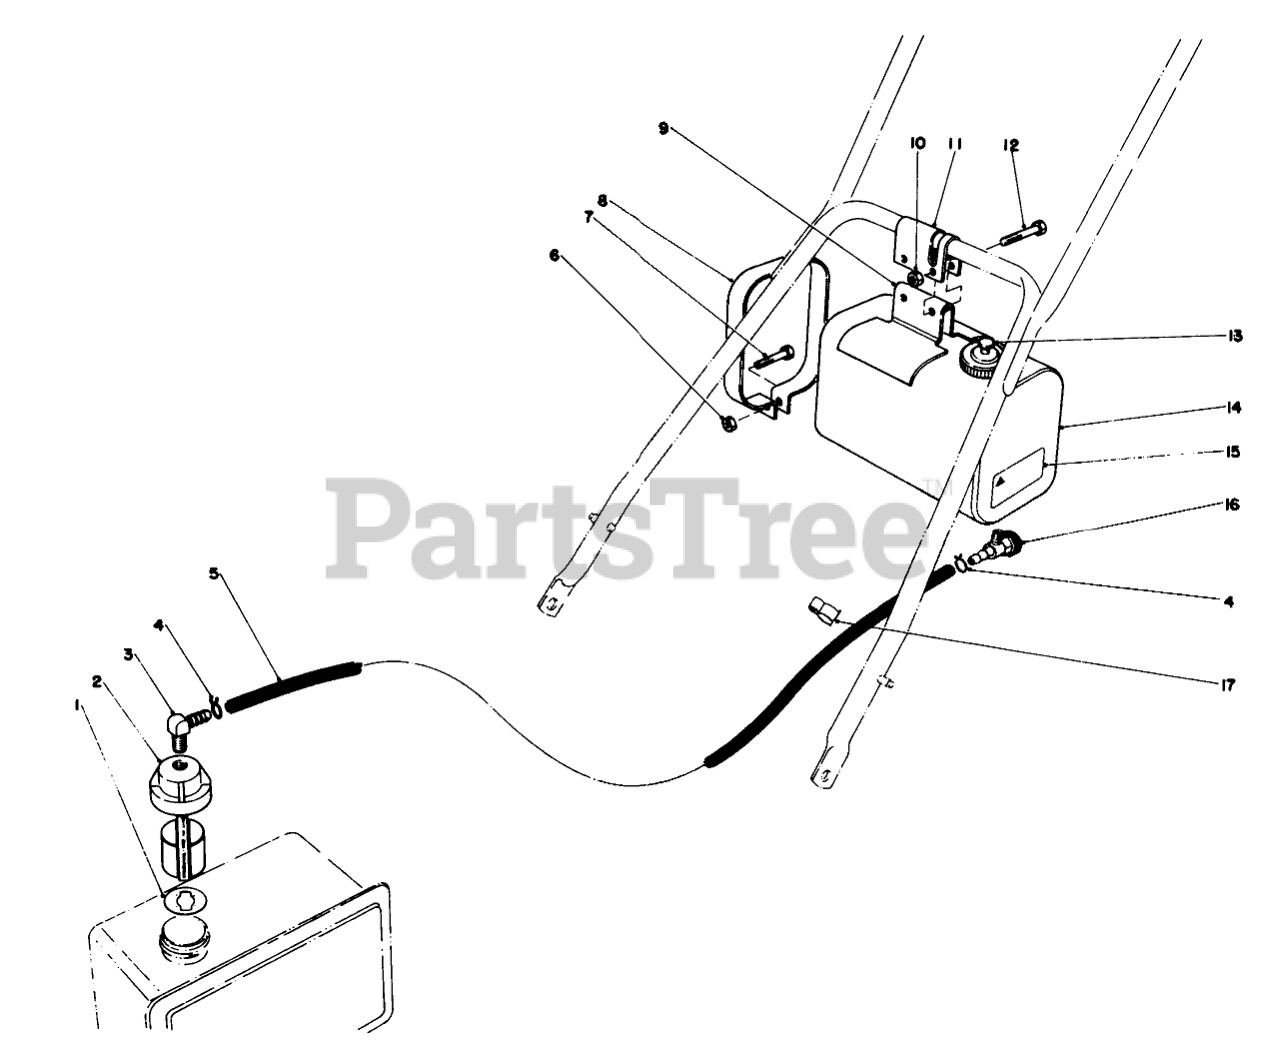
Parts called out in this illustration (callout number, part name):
1	GASKET
2	Fuel Control Valve (Incl. Ref. #1)
3	CONNECTOR-HOSE
4	Clamp
5	FUEL LINE
6	NUT-LOCK
7	SCREW-HH
8	TANK STRAP
9	FUEL TANK BRACKET
10	Nut
11	Clamp
12	SCREW-HH
14	Fuel Tank (Incl. Ref. #13)
15	Decal-Caution
16	.125 ID SHUTOFF VALVE
17	CLAMP
